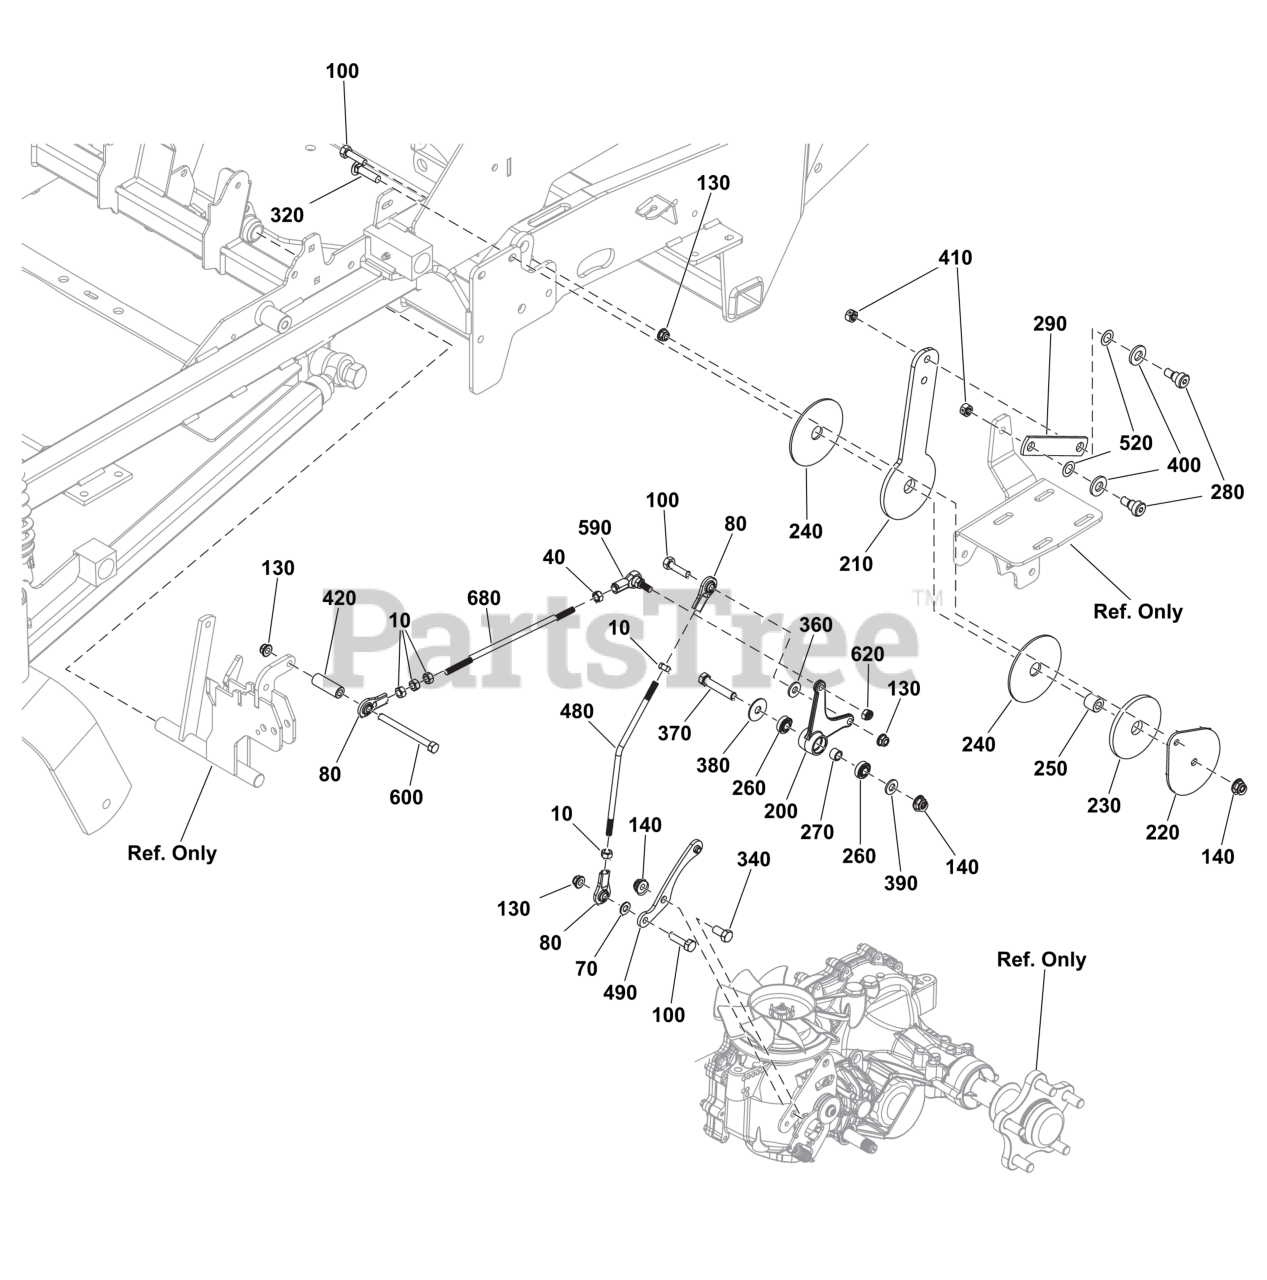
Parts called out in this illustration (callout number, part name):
40	NUT, 5/16-24 HEX, LH
70	WASHER
80	JOINT-BALL
100	BOLT, 5/16-18 X 1-1/4
130	NUT
140	NUT, 3/8-16 HEX NYLOCK
200	PIVOT, CONTROL SYSTEM
210	PLATE, CONTROL SYSTEM ARM - HT
220	PLATE, CTRL SYSTEM LK
230	PAD, .77 X 3.50 X .25
240	PAD, CONTROL SYSTEM
250	SPACER, .39X.75X.69
260	BEARING, .375ID
270	SPACER, .39X.55X.38
280	BOLT, 3/8-16 X 3/8",
290	LINK, CONTROL SYSTEM, 800/P1 - BLK
320	BOLT, 3/8-16 X 1-1/2
340	BOLT, 3/8-16 X 3/4" G
360	WASHER, 5/16" GD.9 FL
370	CAPSCREW, 3/8-16X2
380	WASHER, 3/8" FENDER
390	WASHER, 3/8"
400	WASHER, 1/2" YELLOW
410	NUT, 3/8-16 HEX SIDE
480	ROD, LOWER CONTROL, 800/P1 CONSOL
490	ARM-CONTROL
520	WAVE WASHER
590	JOINT-BALL
600	BOLT, 5/16-18
620	NUT, 5/16-24 HEX NYLO
680	ROD, 5/16-24 RH & LH, BZ
